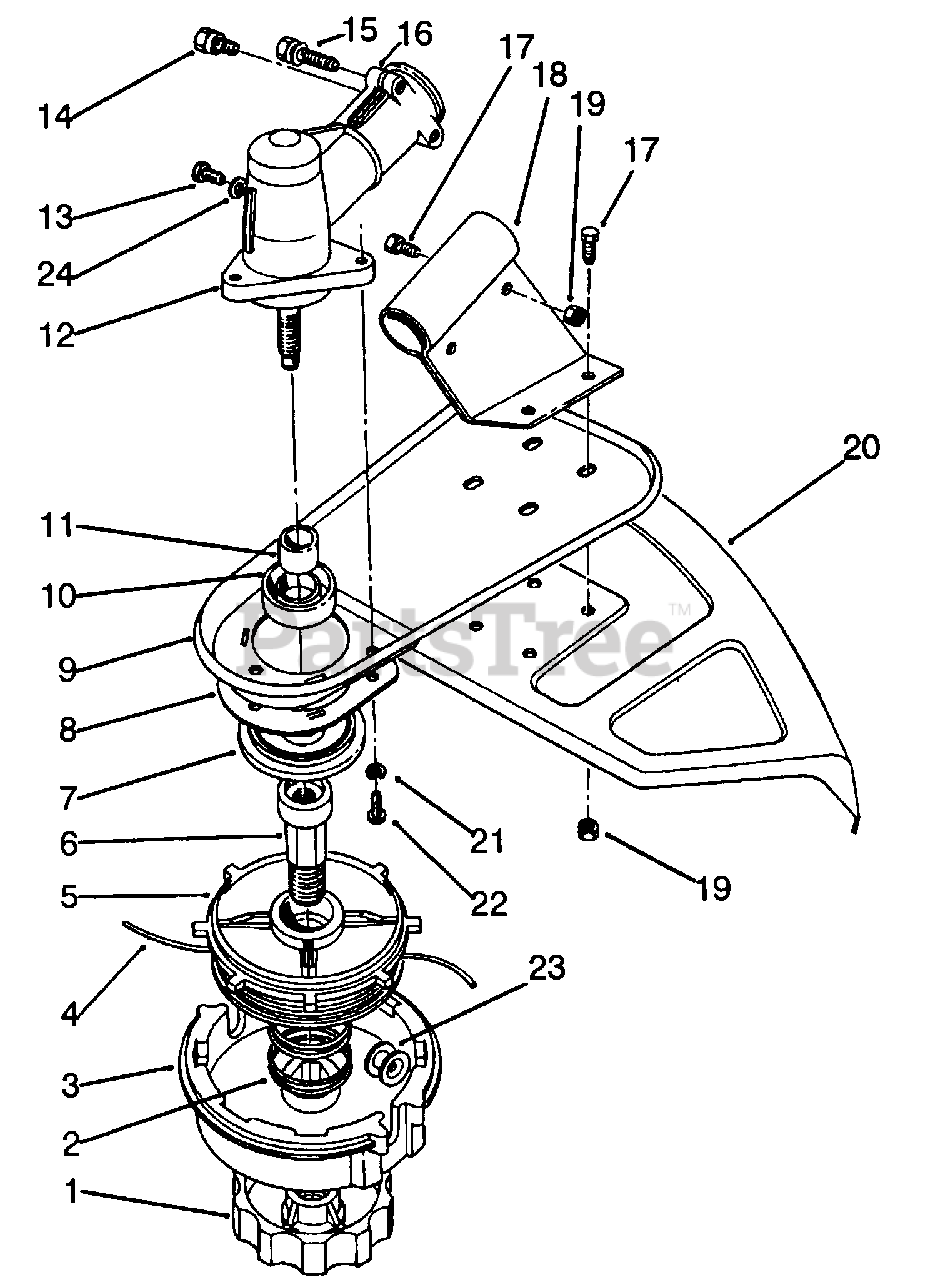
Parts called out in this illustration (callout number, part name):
1	Knob-L.H.
3	Spool-Housing Assembly Line Cutting .105 Dia.11'
4	Line-Cutting .08 Dia. (38' Optional)
5	Spool-Inner
7	Cap-Dust
8	Guard-Grass Wrap
9	Support-Shield
10	Seal-Oil
11	Sleeve-Spline
12	Gear Box Assembly (Incl. Ref. #10, 11, 13-16 & 24)
13	Screw Hex. Hd.
14	Screw-Hex. Hd.
15	Screw-Hex. Hd.
16	Washer-Flat
17	Screw-Hex. Hd.
18	Bracket-Shield
19	Nut-Lock
20	Shield-Grass
21	Washer-Lock
22	Screw-Guard
